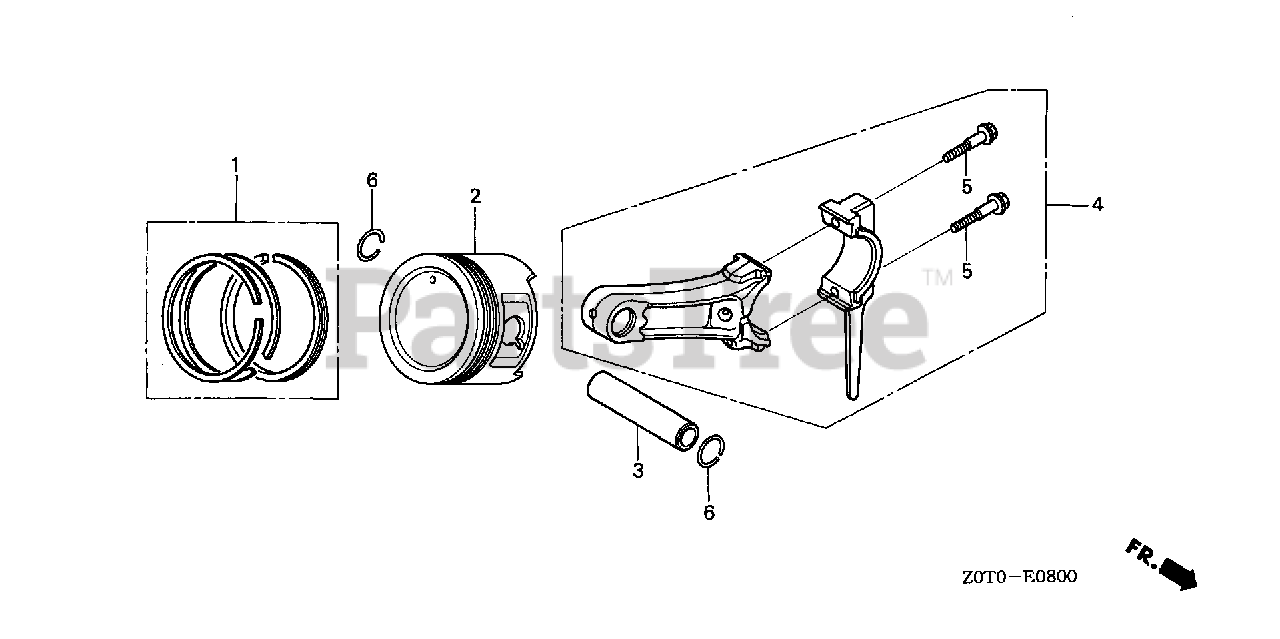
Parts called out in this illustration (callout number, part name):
1	RING SET, PISTON (STD) (RIKEN)
1	RING SET, PISTON (0.25) (TPR)
1	RING SET, PISTON (0.25) (RIKEN)
1	RING SET, PISTON (0.50) (TPR)
1	RING SET, PISTON (0.50) (RIKEN)
2	PISTON (STD)
2	PISTON (0.25)
2	PISTON (0.50)
3	PIN, PISTON
4	ROD ASSY., CONNECTING
4	ROD ASSY., CONNECTING (UNDER SIZE)
5	BOLT, CONNECTING ROD (6X34.5)
6	CLIP, PISTON PIN (18MM)
